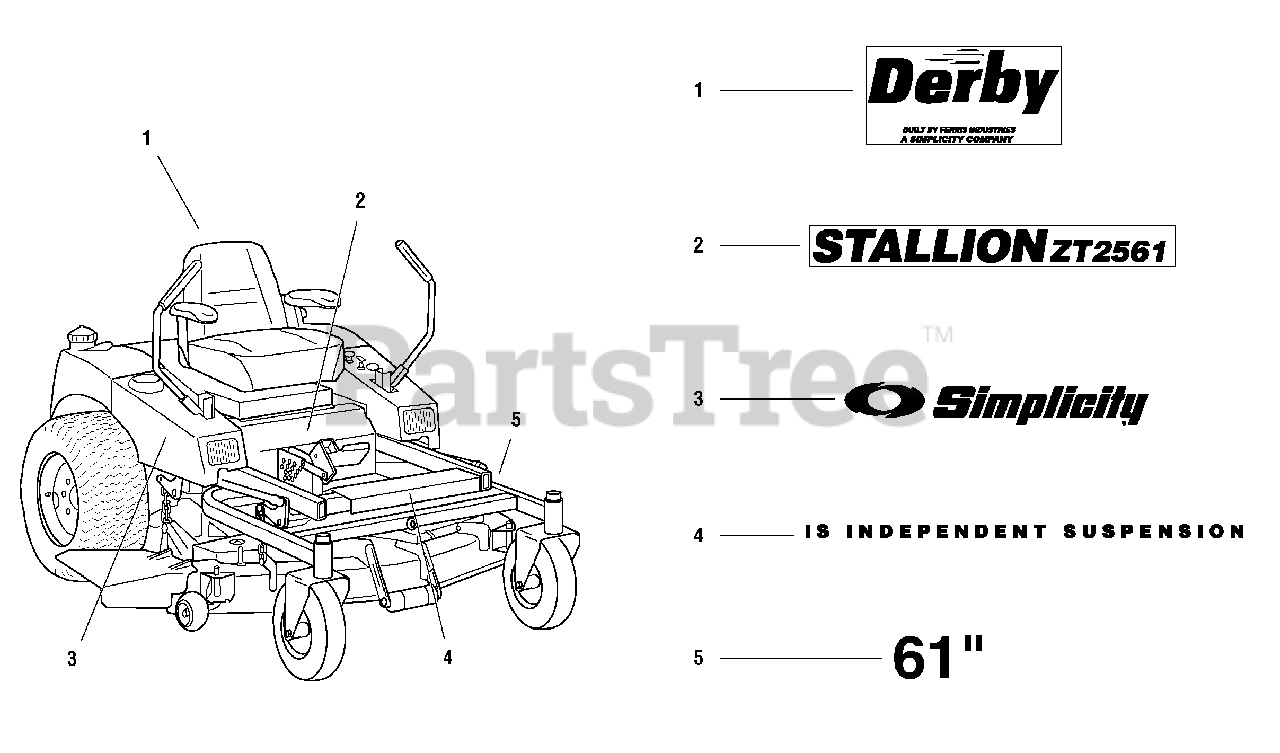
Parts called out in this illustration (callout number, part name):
1	DECAL, Derby Built By Ferris (located on back of seat)
2	DECAL, Stallion ZT2561
3	DECAL, Simplicity Logo
4	DECAL, IS Independent Suspension
5	DECAL, 61" (LH guard end)
